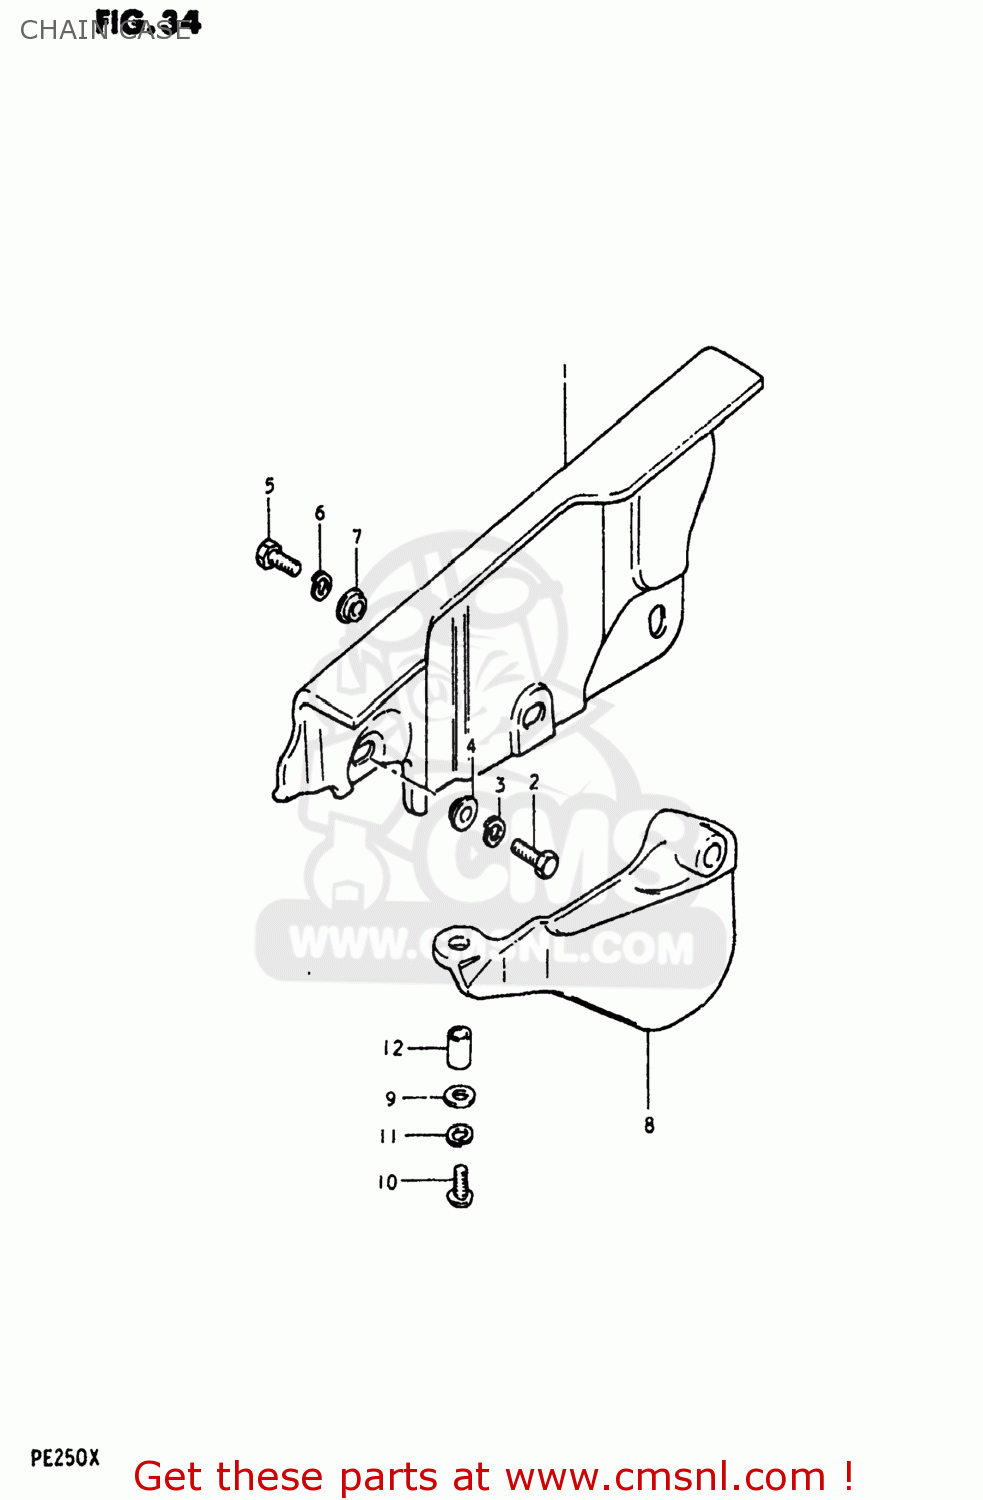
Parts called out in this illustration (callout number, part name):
1	CASE,CHAIN
2	BOLT, UPPER
3	LOCK WASHER
4	WASHER(6.5X18X1)
5	BOLT
6	LOCK WASHER
7	WASHER
8	RUBBER,CHAIN CASE,LOWER
9	WASHER(6.5X18X1)
10	SCREW 6X12
11	LOCK WASHER
12	SPACER (6.1X8X5.2)
